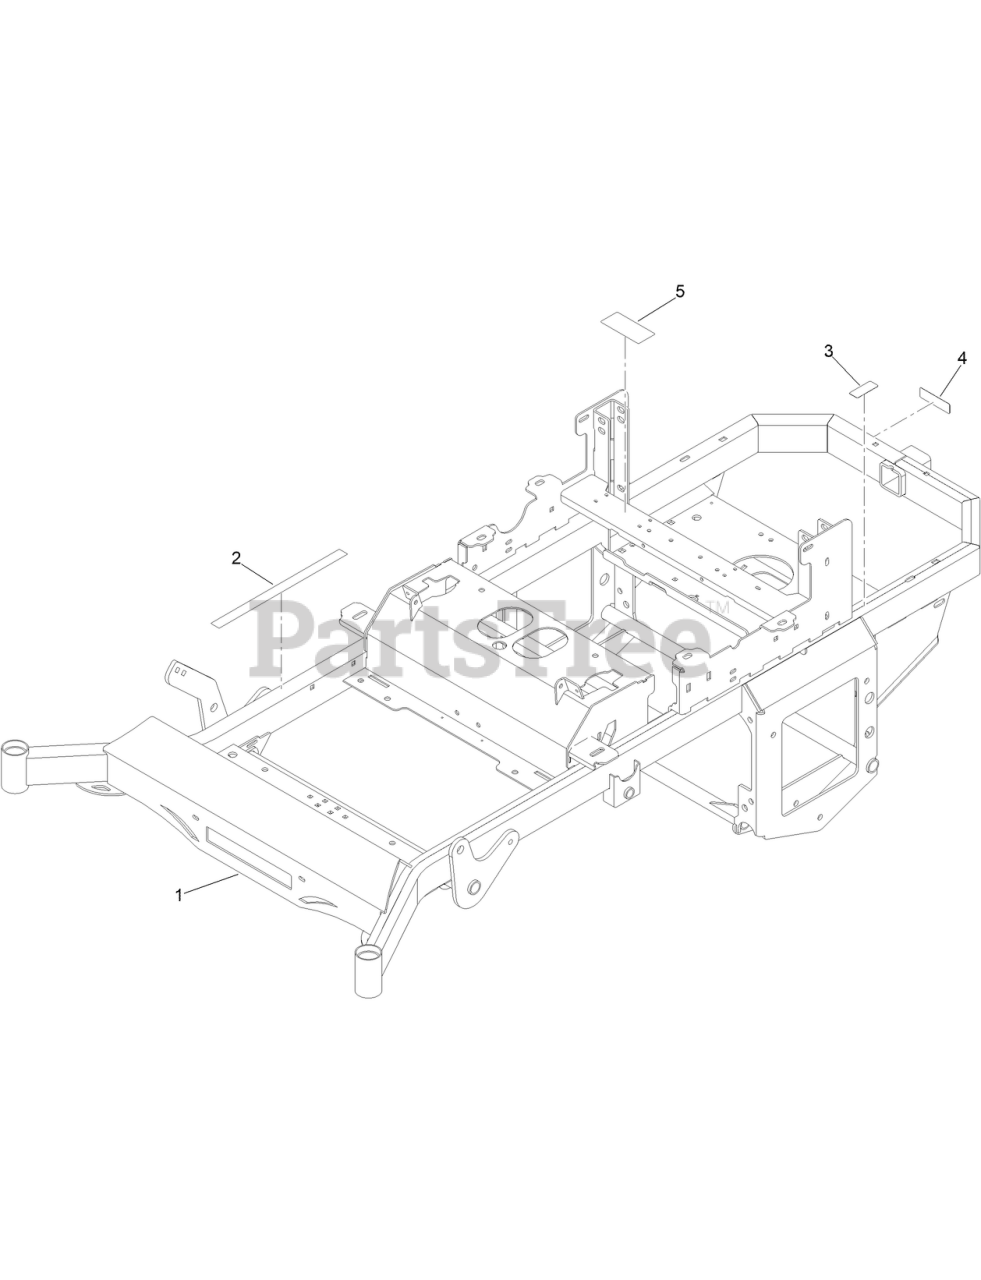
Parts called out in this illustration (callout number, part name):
1	FRAME ASM
2	DECAL-WARNING(AURORA)
3	DECAL-HOT SURFACE
4	DECAL-HITCH
5	DECAL-ROTATING FAN HAZARD
